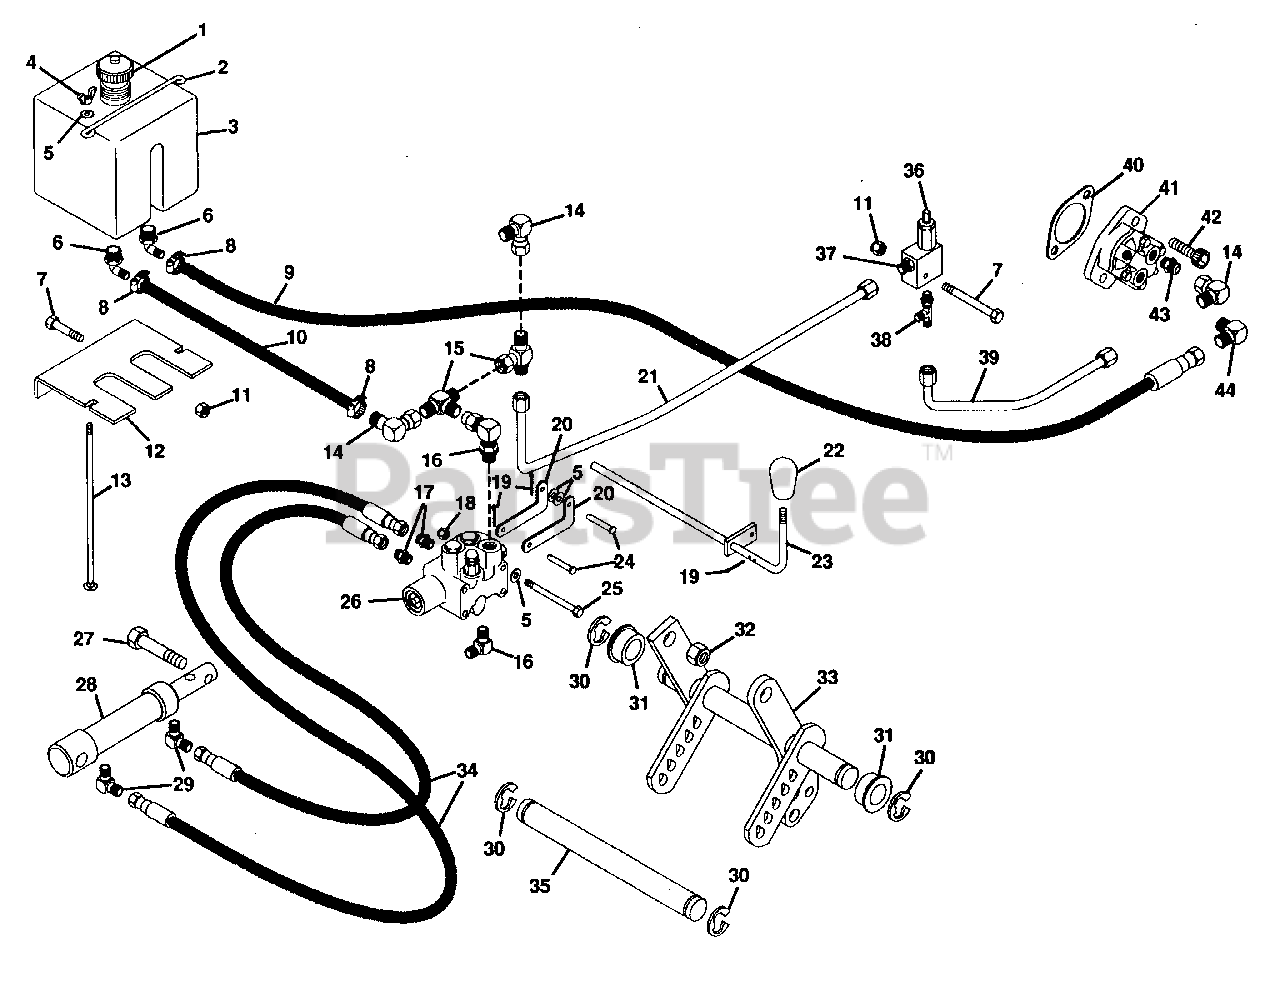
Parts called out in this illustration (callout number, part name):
1	CAP, TANK
2	ROD, OIL TANK HOLD-DOWN
3	TANK, HYDRAULIC
4	NUT, WING 1/4-20
5	WASHER, FLAT .281X.625X.065
6	FITTING MALE ELBOW 1/2X1/2
7	BOLT, HEX 5/16-18X.75
8	CLAMP, .88 DIA. HOSE
9	HOSE, TANK TO PUMP
10	HOSE, LIFT VALVE TO TANK
11	NUT, LOCK 5/16-18
12	SUPPORT, HYDRAULIC OIL TANK
13	BOLT, 1/4-20X8.00 RD HD SQ NK
14	ADAPTOR(P-H #3903-6-6)
15	ADAPTER, T. FLEX
16	ADAPTOR(P-H #2503-6-6)
17	ADAPTOR(P-H #0503-4-4)
18	NUT, LOCK 1/4-20
19	PIN, COTTER .094X.75
20	ROD, HYDRAULIC CONTROL
21	LINE, VALVE TO TANK
22	KNOB, PTO
23	WELDMENT, HYDRAULIC CONTROL ROD
24	PIN, CLEVIS
25	BOLT, HEX 1/4-20X2.75
26	VALVE, HYDRAULIC
27	BOLT, HEX 1/2-13X2.00
28	CYLINDER, HYDRAULIC
29	ADAPTOR(P-H #2503-4-4)
30	E-RING, 1.000 SHAFT
31	BUSHING, PIVOT
32	NUT, LOCK 1/2-13
33	WELDMENT, LIFT LEVER SHAFT
34	HOSE, HYDRAULIC 14.5
35	SHAFT, HYDRAULIC CYLINDER
36	VALVE, PRESSURE RELIEF
37	ADAPTER,(P.H. #0503-6-6)
38	ADAPTOR
39	LINE, PUMP TO VALVE
40	GASKET, COVER PLATE
41	PUMP, HYDRAULIC
42	SCREW, CAP 3/8-16 HEX SOCKET HD
43	ADAPTOR
44	ADAPTOR(P-H #0503-10-6)
